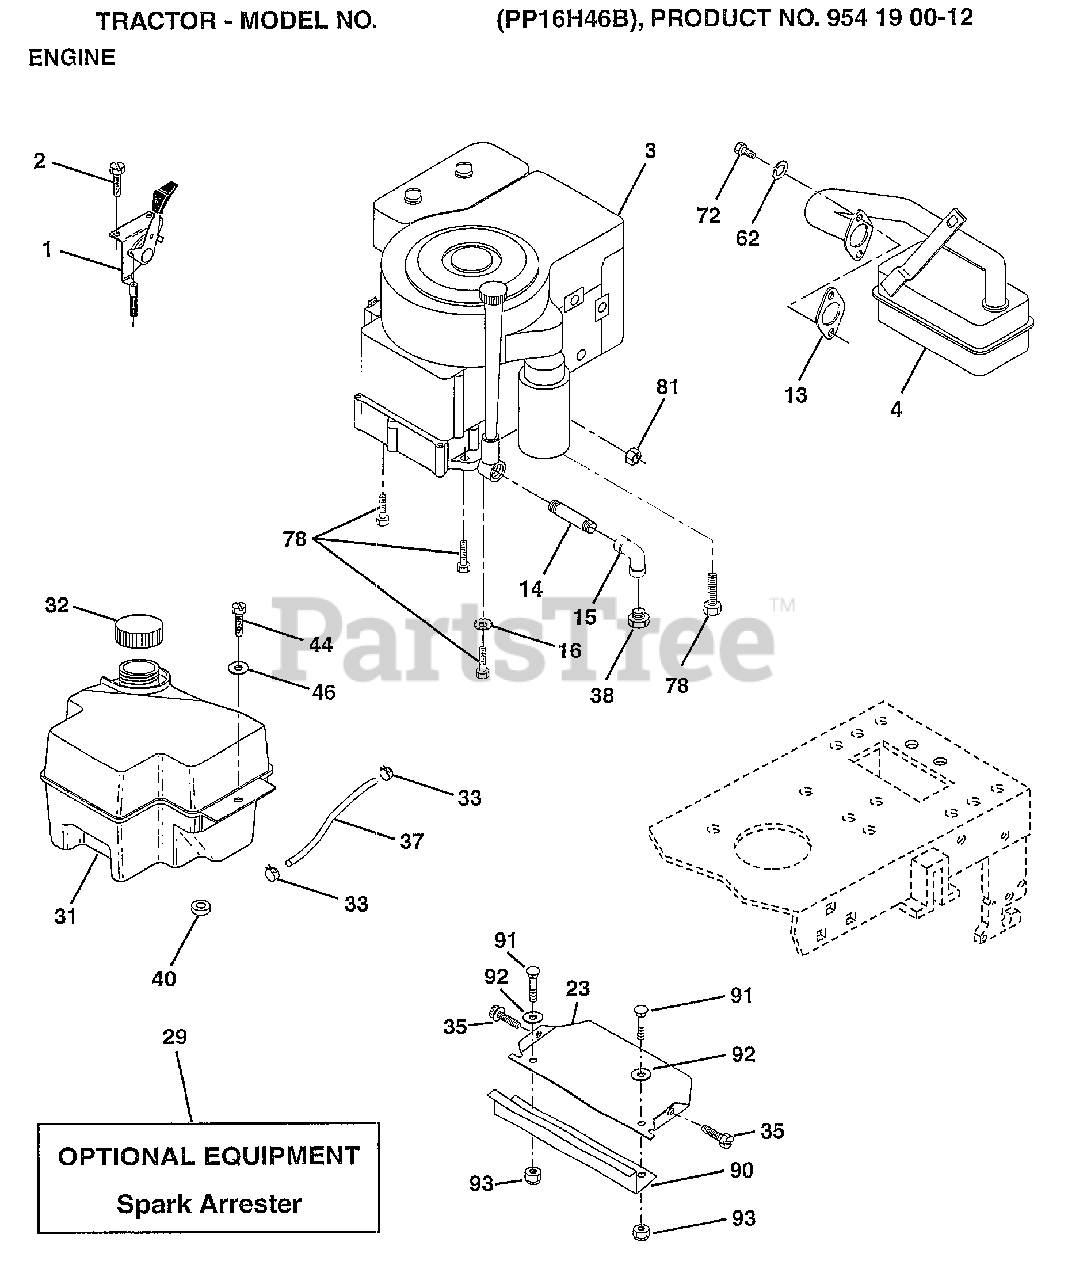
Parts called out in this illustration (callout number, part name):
1	CONTROL THROTTLE
2	SCREW LT
4	MUFFLER
13	GASKET ENG 1 313 LD TIN PLATED
14	PIPE NIPPLE
15	ELBOW
16	LOCKWASHER
23	SHIELD-HEAT
32	CAP ASM FUEL
33	HOSE CLAMP
35	SCREW
37	LINE FUEL
44	SCREW HEX CRT
46	WASHER
49	SCREW GTV
62	LOCKWASHER
72	SCREW
78	SCREW
81	NUT
90	GUARD-DEBRIS
91	BOLT BLK FIN HEX 1/4-20 UNCX 1/2
92	WASHER
